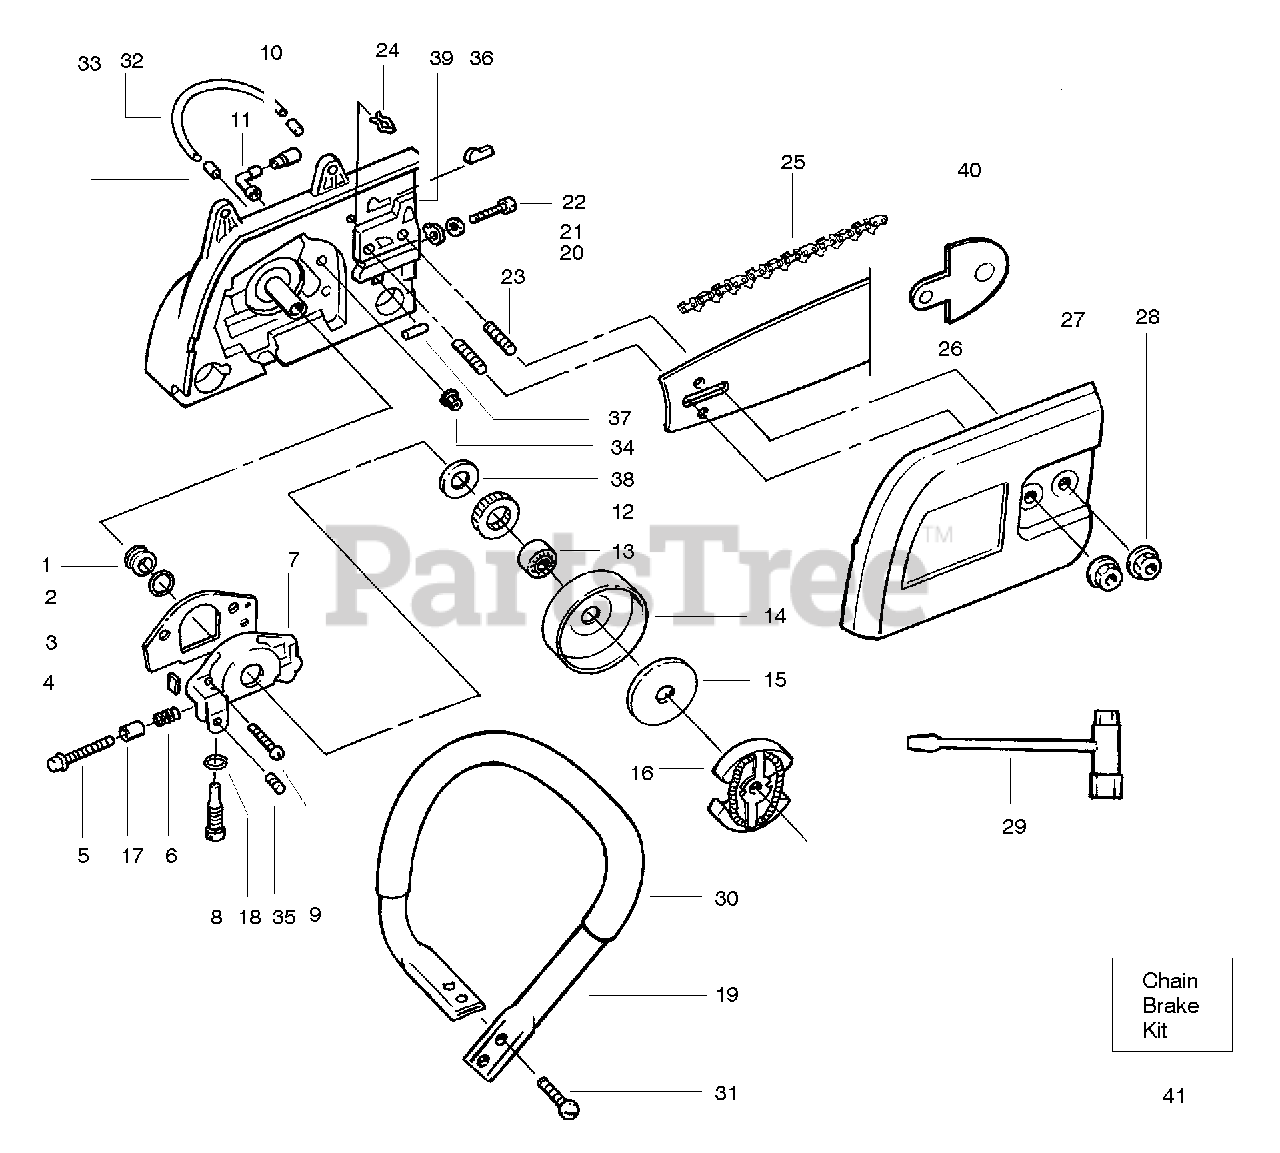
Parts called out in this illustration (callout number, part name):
1	Worm Gear
3	Engine Gasket Set
4	Dust Plug
5	Shaft Ass'y.
7	Oil Pump Kit
8	Screw-Oiler Adjusting
9	Screw
10	Oil Pickup & Filter
11	Oiler Intake Line
12	Rim Sprocket Model 336
12	Rim Sprocket Model 365
14	Drum Sprocket
15	Clutch Plate
16	Clutch Ass'y.
17	Oiler Gear Spur
18	"O" Ring
19	Handlebar Ass'y.
20	Bar Adjusting Pin
21	Retainer-Bar Adjust
23	Bar Stud
24	Vent Pin
25	Chain Model 336-16"
25	Chain Model 336-20"
25	Chain Model 365-16"
25	Chain Model 365-20"
26	Bar Model 336-16"
26	Bar Model 336-20"
26	Bar Model 365-16"
26	Bar Model 365-20"
27	Bar Clamp
29	Scrench Silver Finish (1/2")
29	Scrench Gold Finish (9/16")
30	Handlebar Grip
32	Oiler Discharge Line
33	Oiler Discharge Sleeve
34	Tubing Nut
35	Oiler Adjustment Pin
36	Chain Pad-Top
37	Chain Pad
38	Washer-Thrust
39	Crankcase Plug
40	Replaceable Sprocket Nose
41	Chain Brake Kit
